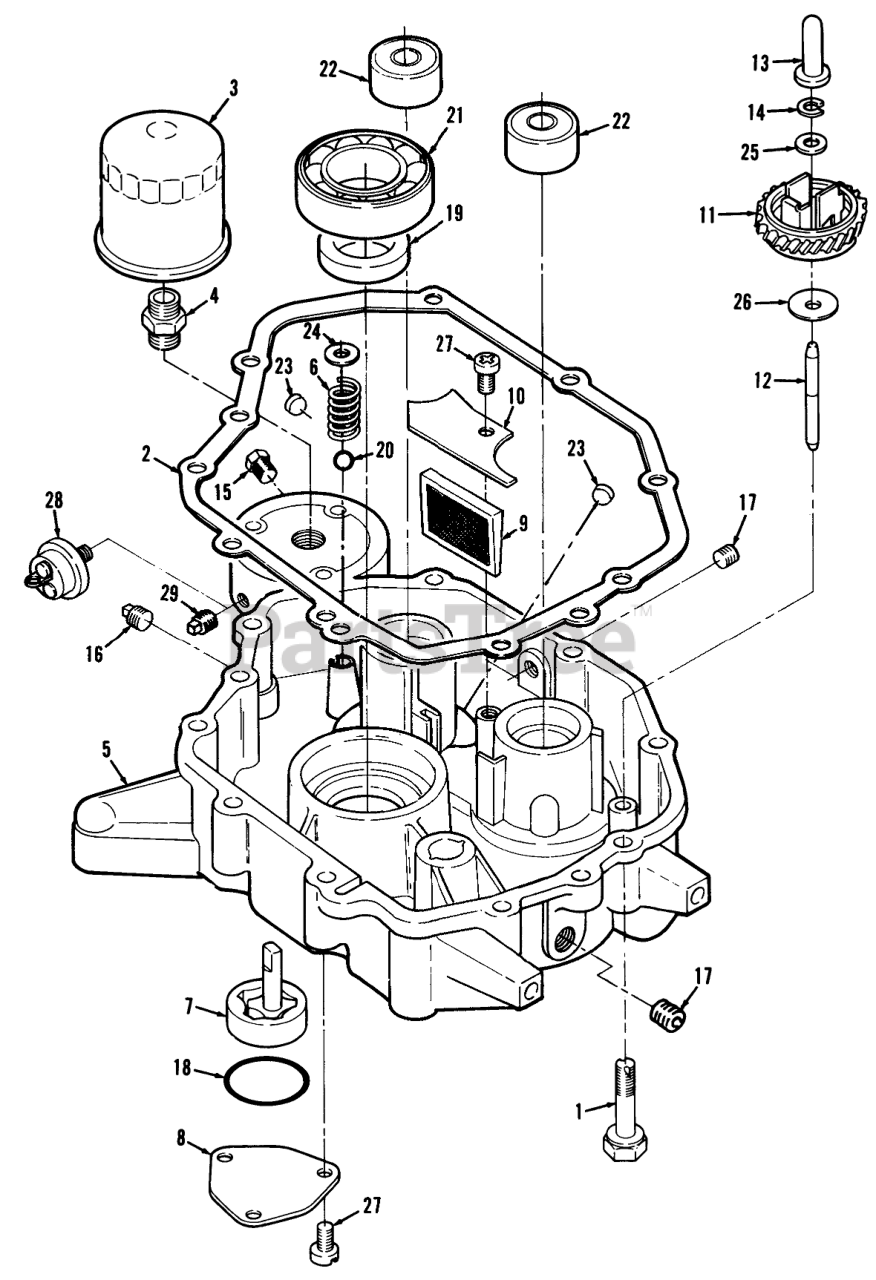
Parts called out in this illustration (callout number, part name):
1	SELF-TAP BOLT SP M8
2	Gasket
3	FILTER
4	ADAPTER
5	BASE-0IL
6	Spring
7	PUMP-OIL
8	COVER-OIL PUMP
9	SCREEN
10	COVER
11	GEAR-GOVERNOR
12	SHAFT-GOVERNOR
13	Sleeve
14	STOP-GOVERNOR
15	PLUG-HEX HD
16	PLUG - SQUARE HEAD
18	RING-O
19	SEAL-OIL CRNKSHFT UP
20	BALL-BEARING
21	BRNG-BALL CRANKSH L
22	BRNG-BALL BAL SHFT L
23	PLUG-CORE HOLE
24	RETAINING-RING
25	WASHER-1.6MM THK
26	WASHER-1MM THK
27	SCREW-M6 X 14
28	SWITCH-OIL PRESSURE
29	Plug
